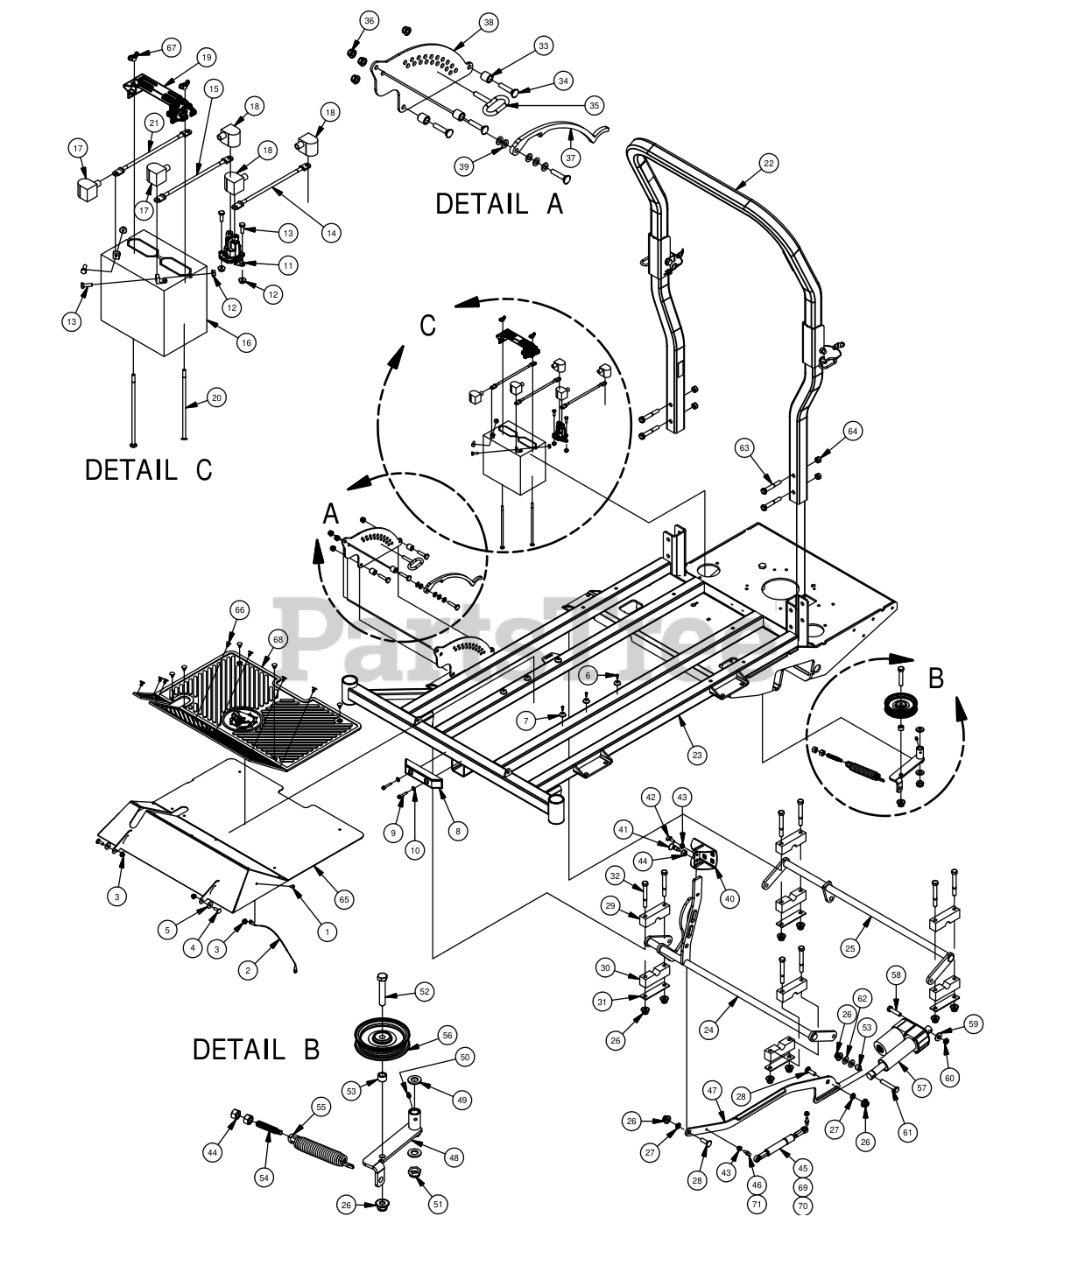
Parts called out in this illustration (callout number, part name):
1	1/4" x 5/8" BS C/S 18-8 SS
2	Floor board Cable W/ Swivel Ends
3	5/16" Nylock Flange Nut Zinc
4	5/16" x 1" Carriage Bolt
5	.360 ID Plastic Washer
6	#10 x 1/2" Self Tapping Screw
7	Button Bumper
8	8" Rubber Bumper
9	1/4" x 1 1/2" Self Tapping Screw
10	1/4" Flat Washer
12	1/4-20 Hex Flange Nuts Zinc w/Serrations
13	1/4-20 x 3/4 GR 5 Hex Bolts Zinc
14	Red Battery Cable Alternator to Starter Cable
15	12 in red battery cable
17	Black Boot For Ground Cable
19	Battery Hold Down
20	1/4-20 X 8 Carriage Bolt
21	Ground Cable
22	2015 Outlaw 2x2 Folding ROPS
23	2015 XP Frame
24	2015 Outlaw Act Bar Assembly (Front)
25	2015 Outlaw Act Bar Assembly (Rear)
26	1/2-13 Nylon Flange Nut
27	Bushing- SF-1620-4
28	1/2 x 1-1/2 Carriage Bolt
29	Two Piece Pillow Block (Male)
30	Two Piece Pillow Block (Female)
31	Two Piece Pillow Block Strap
32	1/2" x 4" Bolt (Grade 8)
33	Spacer 3/4 OD x 1/2 ID x 3\4 Length
34	3/8 x 1 3/4 Carriage Bolt
35	Deck height lever pin
36	3/8" Nylock Flange Nut
37	Outlaw Deck Lever Lock
38	Outlaw Height Indicator Plate (Outer)
39	.390 x .750 x .062 Nylon Washer
40	Outlaw Deck Lift Pedal
42	5/16-18 x1 Thumb Screw Zinc
43	5/16" Flange Nut
44	1/2" Hex Nut
45	200 lb Gas Spring- 54" Deck outlaw
46	10mm Damper Ball Stud-XP Linkage
47	Outlaw Linkage Bar Susp Frame
48	Pump Idler Bracket
49	.630 ID Plastic Washer
50	1/4" Press in Grease Fitting
51	5/8" Nylock (1/2 Jam)
52	1/2" x 2 3/4" Hex Bolt
53	1/2 x 1/2 Spacer
54	All Thread-Pump Idler Tensioner
55	2009 Deck/Pump Idler Spring
56	4 3/4" Idler Pulley
58	1/2-13x2 Grade 8 Hex Bolt
59	1/2" Washer (Grade 8)
60	1/2" Nylock Nut (1/2 Jam)
61	1/2" x 3" Hex Bolt
62	.505 Nylon Spacer
63	1/2-13 X 3.25 Hex Bolt - Grade 5
64	1/2" Center Lock Nut
65	2016 Outlaw Floor Panel
66	5/8" Christmas Tree Fastener
67	1/4" Wing Nut
68	2016 Outlaw Floor Mat
69	250 lb Gas Spring 61" Deck Outlaw
70	300 lb Gas Spring 72" Deck Outlaw
71	13mm Ball Stud (72" Deck Only)
